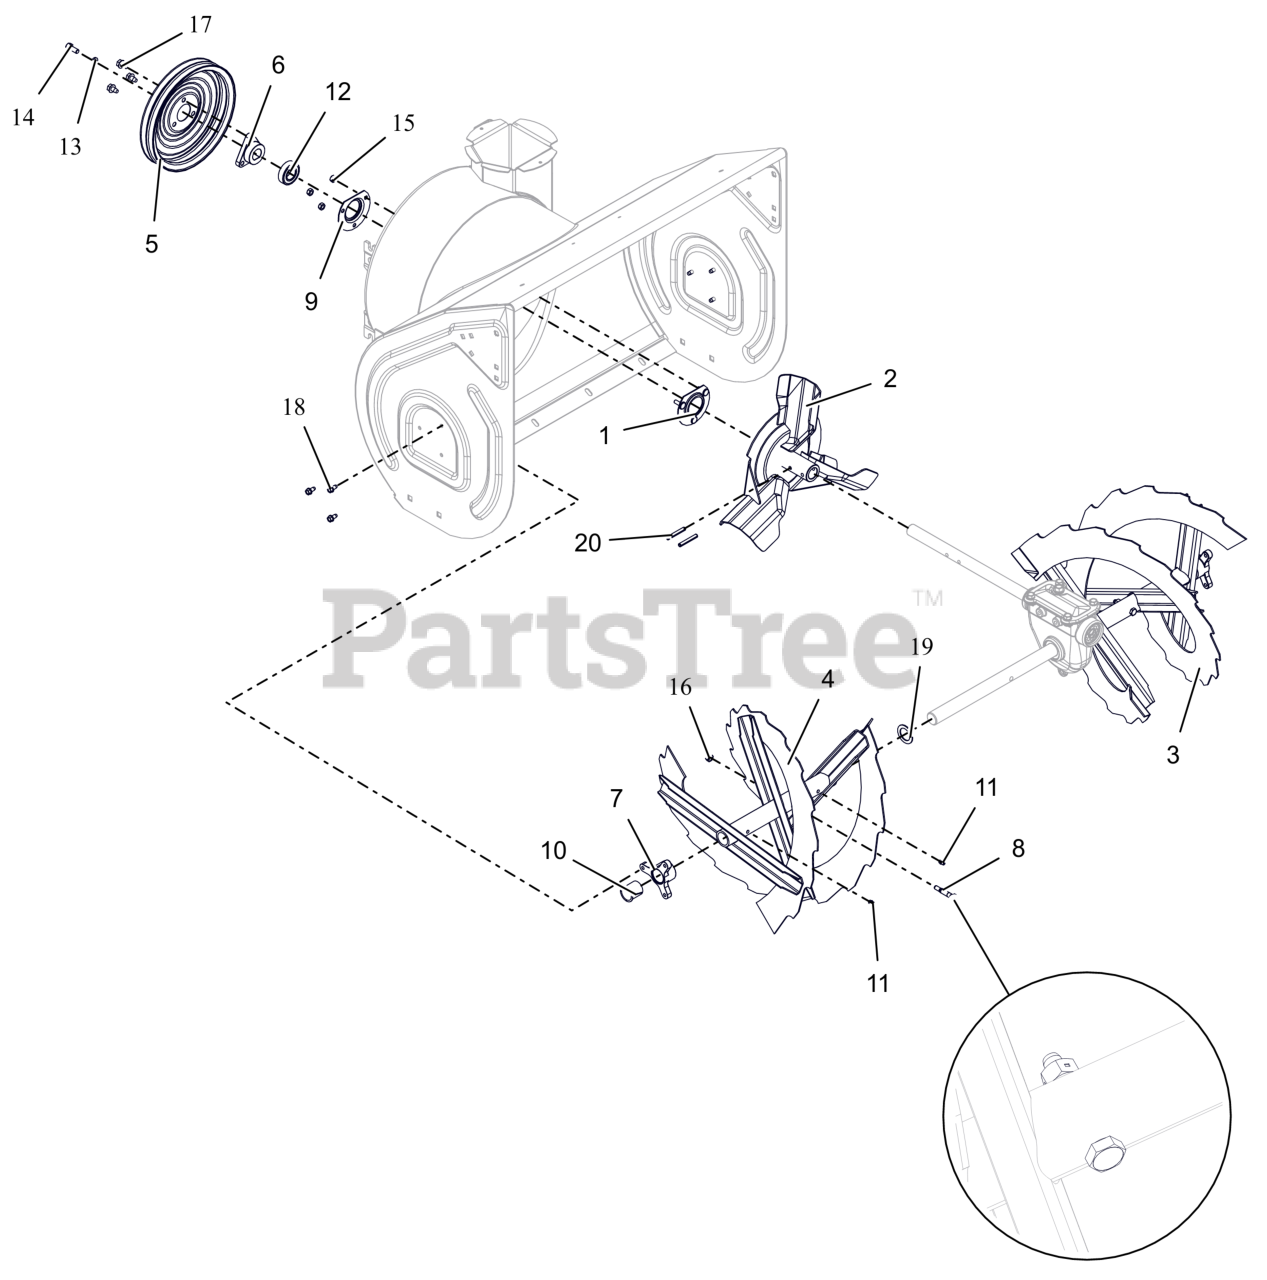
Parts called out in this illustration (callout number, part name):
1	BEARING FLANGE
2	IMPELLER, 3 BLADE-14"
3	RAKE, LH-28"(1 ID X 15.75 OD)
4	RAKE, RH-28"(1 ID X 15.75 OD)
5	PULLEY, SPIN FORM DUAL GROOVE
6	PULLEY HUB, D-BORE .87 PRO
7	BUSHING, RAKE SHAFT 1"
8	SHEAR BOLT SERVICE ASSEMBLY (INCLUDES NUT)
9	BEARING FLANGE
10	BSHG-FLG SPLIT NYLINER 1.0" HP
11	ZERK,FITTING .25X.125 DRIVE IN
12	BRG-BALL .876X1.75X.50 RSTFP
13	WSHR, LK-HVY .312X.097 ZCC
14	BLT, HEX .31-24X.750 G5 ZCC
15	NUT,LK-CTR .25-20 GA ZCC
16	NUT,LK-CTR .31-18 GA ZCC
17	SCR,TAP .312-18X.50 HWH TR ZCC
18	SCR-TAP .25-20X.50 HWH ZCC
19	WSHR, FLT 1.010X1.505X.062 ZCC
20	PIN-ROLL .250X1.75
